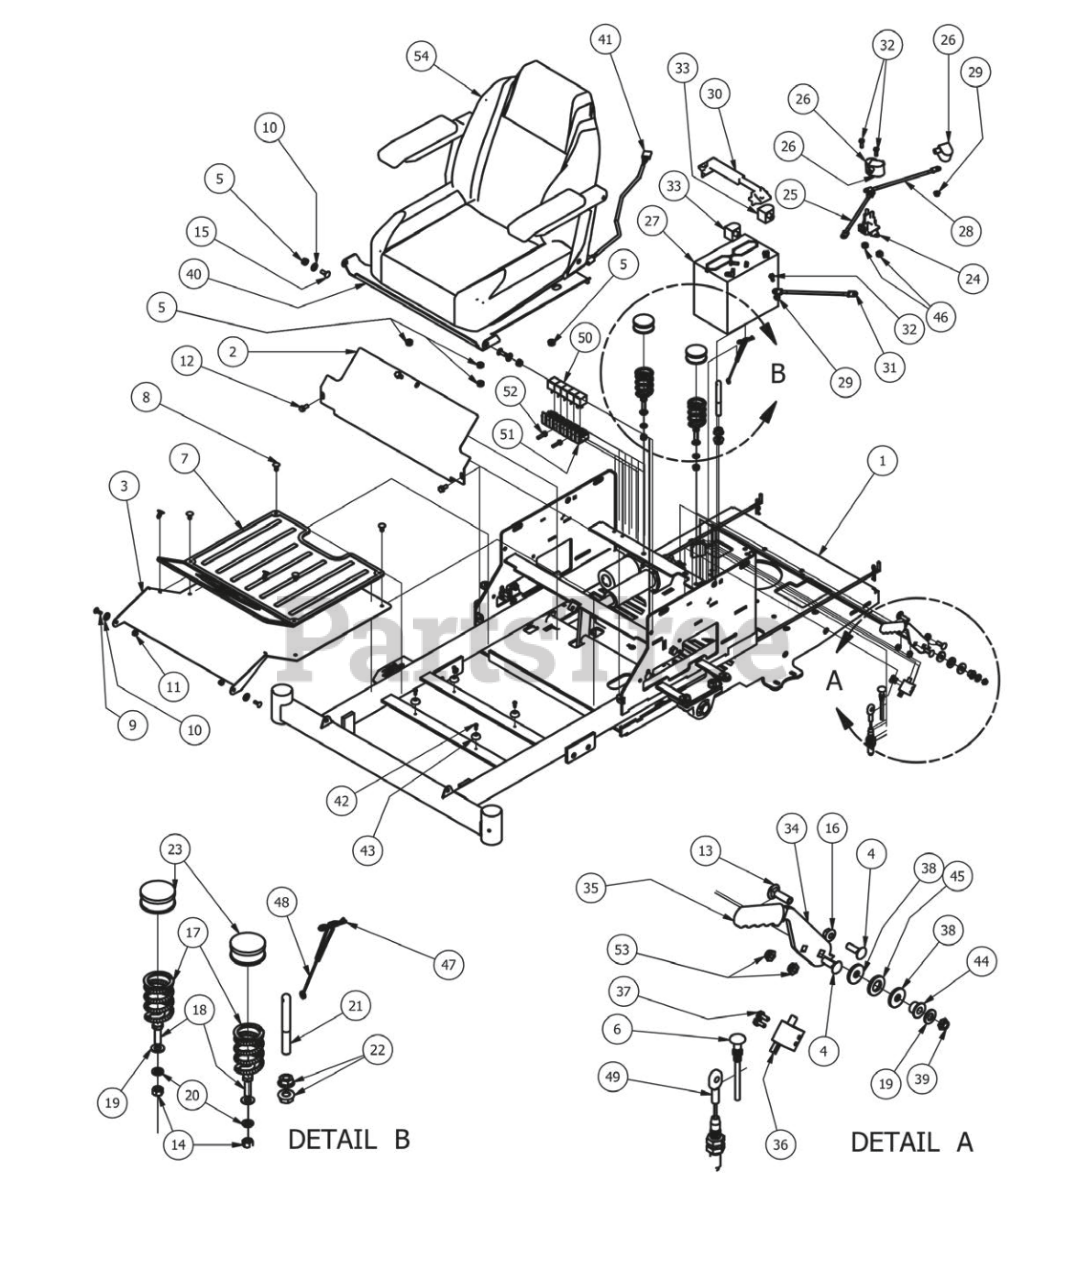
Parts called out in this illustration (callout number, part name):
1	ZT/CZT Frame 2013 Models
2	2013 ZT/CZT Cooler Cover
3	ZT/CZT FLOOR PANEL
4	5/16" x 1" Carriage Bolt
5	5/16-18 Nylon Flange Nut
7	Zt Floorboard Mat
8	Ratchet Fastener
9	1/4" x 3/4" Carriage Bolt
10	.360 ID Plastic Washer
11	1/4" Nylock Nut
12	5/16 x 3/4 washer head type F screw
13	3/8" x 1 1/4" Carriage Bolt
14	3/8" Hex Nut
15	5/16" x 7/8" Carriage Bolt
16	5/16" Flange Nut
17	Seat Spring
18	3/8" x 1 1/4" Hex Bolt
19	3/8" Flat Washer
20	3/8" Lock Washer
21	Seat Braket Pin
22	1/2" Flange Nut
23	Spring Cap Cover
25	24 in red battery cable
27	ZT Battery
28	12 in red battery cable
29	1/4-20 Hex Flange Nuts Zinc w/Serrations
30	Hold Down Assembly
31	Starter to chassis cable
32	1/4-20 x 3/4 GR 5 Hex Bolts Zinc
33	Black Boot For ground cable
34	Brake Handle Cam Over
35	Rubber Brake Grip-cZT/ZT 2013
36	Safety Switch
37	12-24x 1/2 HWH Bolt
38	.390 ID Plastic Washer
39	3/8 Nylock Jam Nut 1/2 Nut
40	2013 ZT Seat Plate
41	Seat Switch Adapter
42	#10 x 1/2" Self Taping Screw
43	Button Bumper
44	Bronze Bushing SF-1220-8
45	.635 ID Plastic Washer
46	3/8" Fine Threaded Jam Nut
47	Seat latch pin
48	seat pin lanyard
49	Brake Cable
50	Relay Terminal
51	Harness-ZT Only 2008 and up
52	1/4 x 1 Hex Head tek screw
53	5/16-18 Nylock Jam Nut 1/2 Nut
54	2013 ZT Seat
